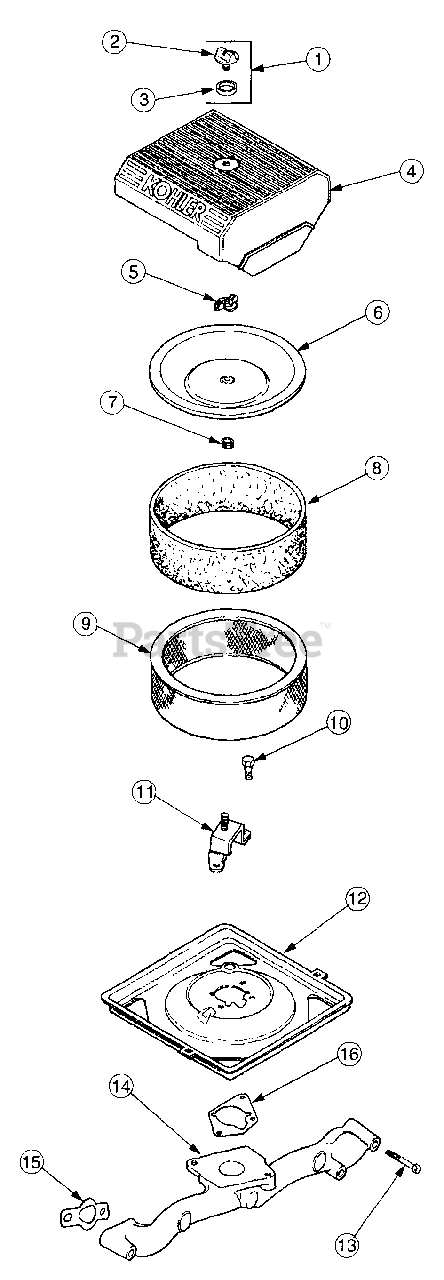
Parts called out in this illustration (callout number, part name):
1	Kit, Knob w/Seal
3	Seal, Air Cleaner Cover Knob
4	Cover, Air Cleaner
6	Cover, Inner Air Cleaner
7	Seal, Inner Air Cleaner
8	Precleaner, Element
9	Element, Air Cleaner
10	Screw, Hex Flange, M6 x 1.0 x 16
11	Bracket, Air Cleaner Base
12	Base, Air Cleaner
13	Screw, Hex Flange, M6 x 1.0 x 55
14	Manifold, Intake
15	Gasket, Intake Manifold
16	Gasket, Air Cleaner Base
